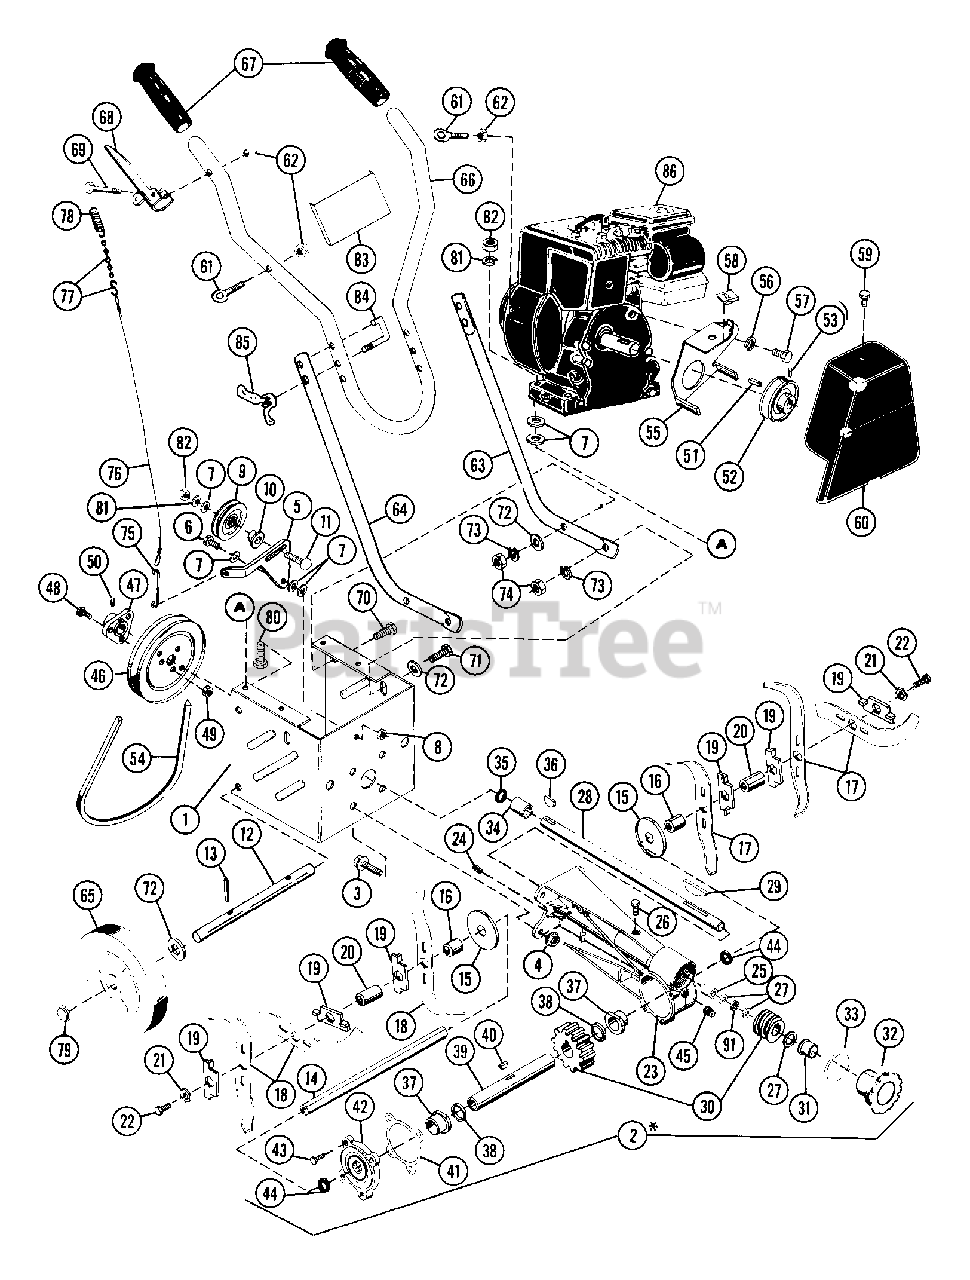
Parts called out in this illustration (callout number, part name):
1	FRAME
2	GEAR CASE - ALUMINUM
3	SCREW - FLG WIZ LOCK HH PL
4	NUT-LK-FLG .375-16 PL
5	IDLER BRACKET
6	BLT-HEX .31-18X1.00 PL GR 2
7	WSHR-FL-STL .38X.875X.083 PL
8	NUT-LK .312-18 GR A PL
9	IDLER
10	SPCR, BRG .315X.50X.688X.281
11	BLT-RDHDSQNK .31-18X1.38SHT PL
12	AXLE ROD
13	PIN-ROLL .125X.75
14	HEX TINE SHAFT
15	DUST CUP
16	SPACER .747X1.002X1.250
17	LEFT HAND TINE
18	RIGHT HAND TINE
19	TINE RETAINER
20	SPACER .747X1.002X1.562
21	WSHR-LK .375X.130
22	BLT-HEX .38-24X.75 GR5
23	GEARCASE - ALUMINUM
24	BREATHER
25	BSHG-SLV .750X1.000X.750
26	BLT-SCRHFWH .38-16X.50 PL
27	WSHR-HDND-THRST .755X1.40X.062
28	WORM SHAFT
29	KEY-FTHR .188X1.38X.188
30	WORM & WORM GEAR SERVICE ASSEM
31	BSHG-FLG .750X1.000X.750X1.132
32	ADJUSTMENT PLUG
34	BSHG-SLV .750X1.000X1.000
35	SEAL .750X1.000X.125
36	KEY-WDRF .188X.875X.375 SAE11
37	BSHG-FLG 1.000X1.25X.75X1.50
38	WSHR-HRD-THRS 1.007X1.542X.062
39	SUB SHAFT
40	KEY-WDRF .188X.625X.25 SAE 61
43	BLT-SERHFWH .31-18X.62 PL
44	SEAL 1.000X1.980X.375
45	PIPE PLUG
47	HUB
48	BLT-SERRDHD SL .31-18X.75 YZ
49	NUT-FLG. .312-18 PL
50	SCR-SET .32-18X.38 SKHCUPNL OH
51	KEY-SQ .188X1.0X.188 SAE 8630
52	ENGINE SHEAVE
53	SET SCREW
54	V-BELT, 4L-RAW EDGE
55	BELT FINGER & COVER BRACKET
56	WSHR-LK .500X.151 HVY PL
57	BLT-HEX .75-16X2.50 PL GR5
58	NUT-SPEED U-TYPE .312-18
59	BLT-HEX .31-18X.50 PL GR2
60	BELT COVER
61	ROD HANGER EYEBOLT
62	NUT-LK-CTR .250-20 PL
63	L H LOWER HANDLEBAR
64	R H LOWER HANDLEBAR
65	TIRE 8X1.75
66	UPPER HANDLEBAR
67	GRIP
68	CLUTCH HANDLE
69	BLT-HEX .25-20X1.50 PL GR5
70	BLT-HEX .38-16X1.75 PL GR2
71	BLT-HEX .38-16X1.00 PL
72	WSHR-FL-STL.406X.812X.065PL
73	WSHR-LK .375X.115 HVY PL
74	NUT-HEX .375-16
76	CLUTCH CABLE
77	CHAIN & CONNECTOR
78	SG-TENS .092X.69X1.75 WLD 54
79	CAP, 3/8 ROD YWZC
80	BLT-HEX .31-18X1.75 PL GR2
81	WSHR-LK .312X.097 PL HVY
82	NUT-HEX .312-18
83	NAME PLATE
85	WING NUT, .312-18
91	BRG-N THRST .754X1.24X.078
